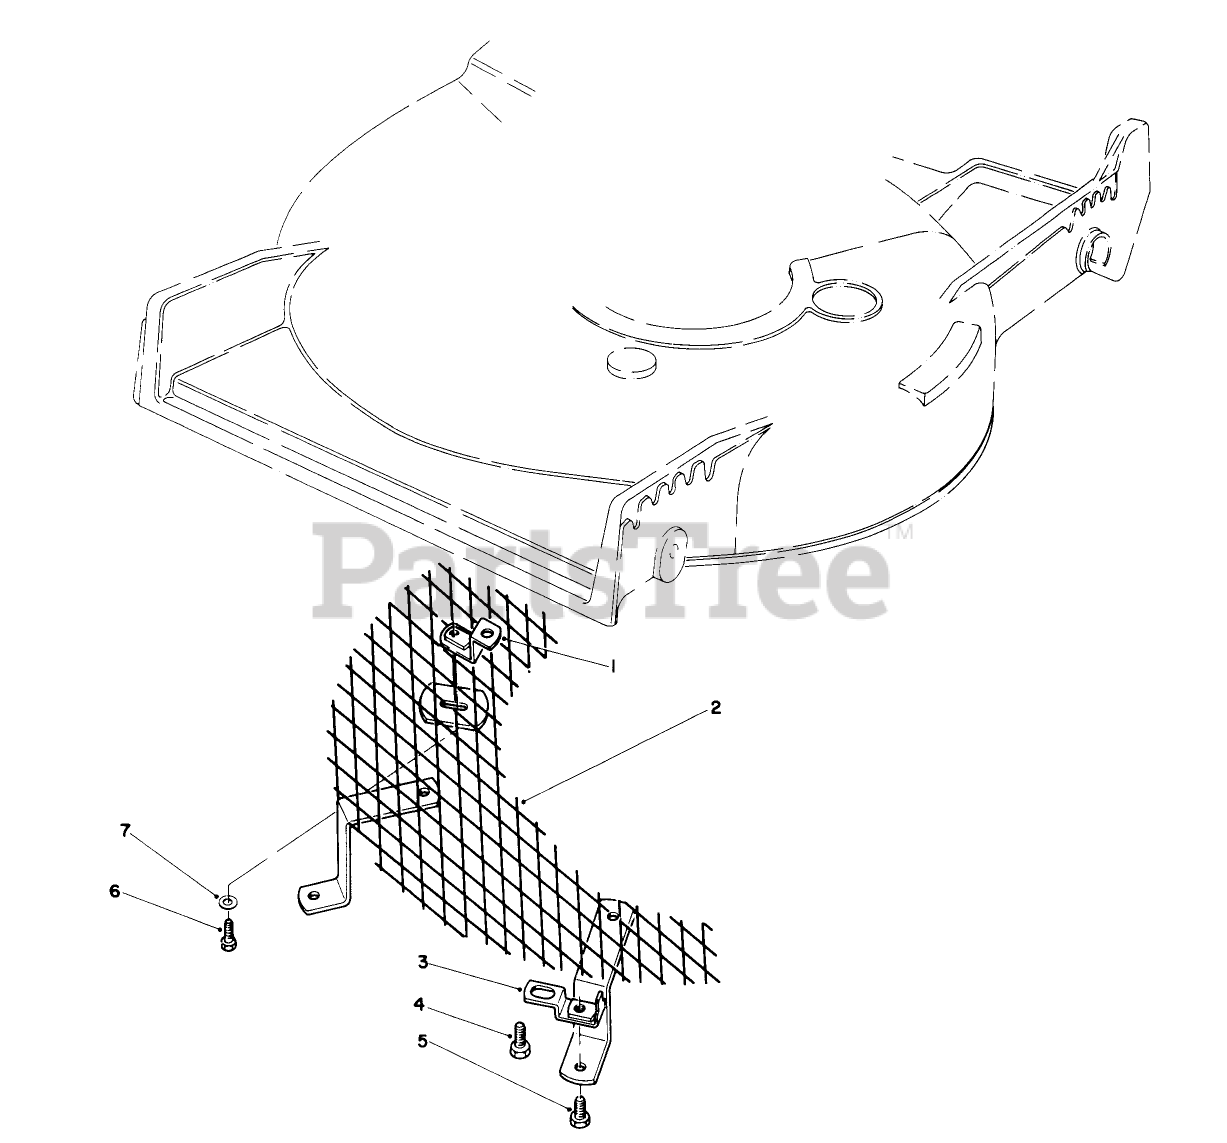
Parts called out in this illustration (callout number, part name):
1	BRACKET WA
2	SCREEN WA
3	MTG. BRACKET W.A.
4	SCREW-HWHTF
5	SCREW-HH
6	SCREW-HH
7	WASHER-FLAT
